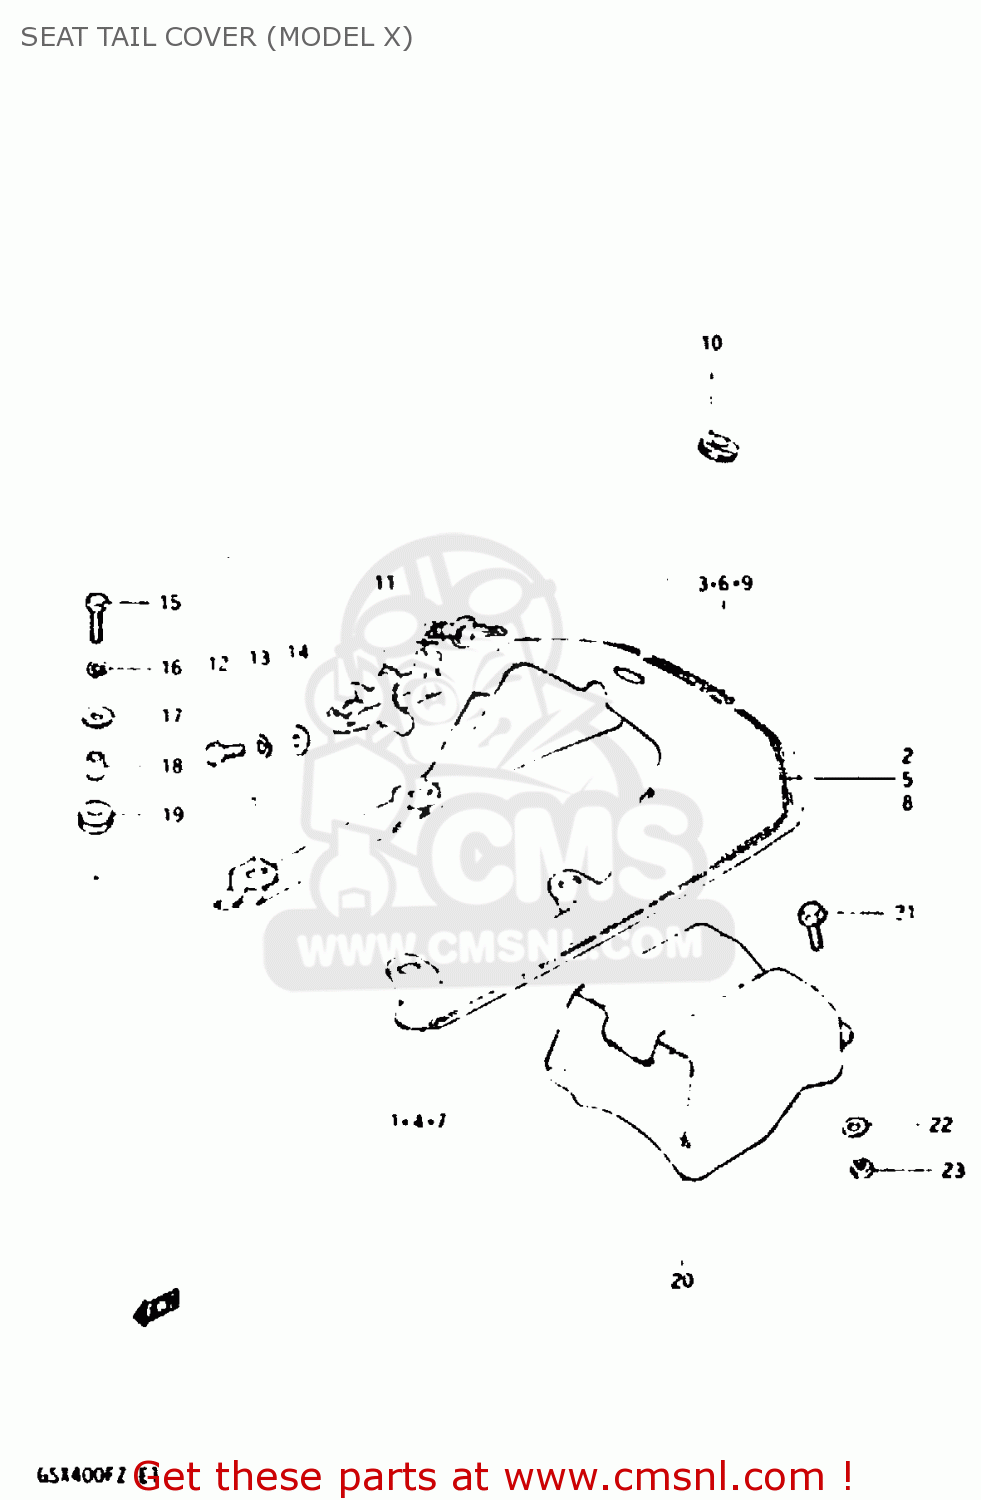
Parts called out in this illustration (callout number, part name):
1	COVER,SEAT TAI
2	TAPE SET
3	EMBLEM,SEAT TAIL(SILVER)
4	COVER, SEAT TAIL (SILVER)
5	TAPE SET
6	EMBLEM (RED)
7	COVER, SEAT TAIL (RED)
8	TAPE SET
9	EMBLEM,SEAT TAIL(SILVER)
10	GROMMET,SEAT LOCK HOLE
11	LOCK SET,SEAT
12	BOLT
13	LOCK WASHER
14	WASHER
15	BOLT
16	LOCK WASHER
17	WASHER(6,5X22X1.6)
18	SPACER(6.5X10.5X12)
19	CUSHION
20	BOX, SEAT TAIL
21	BOLT
22	WASHER
23	NUT
